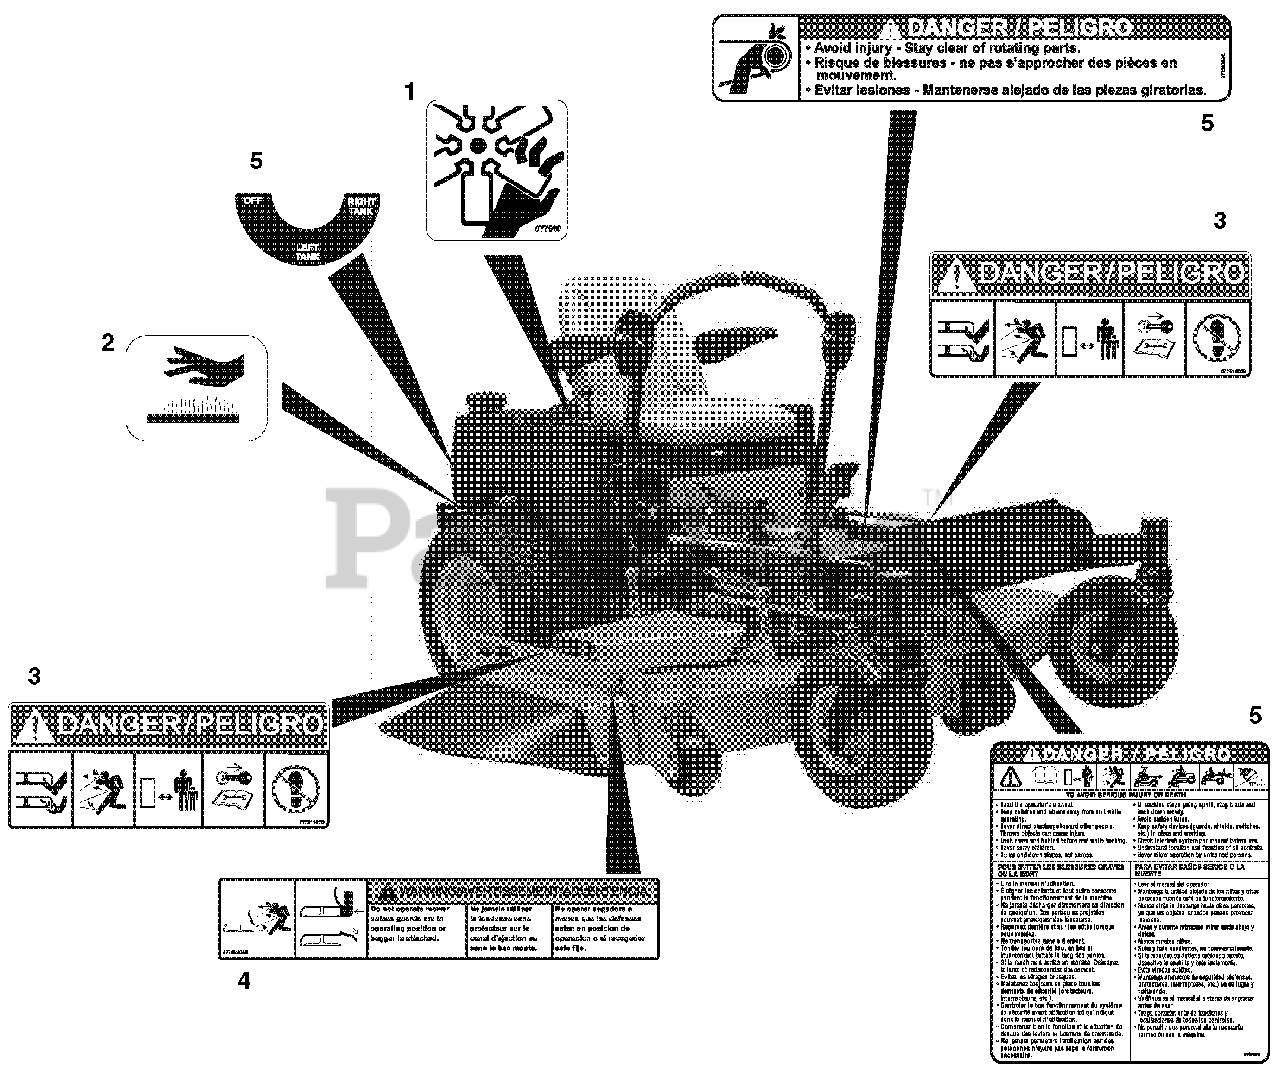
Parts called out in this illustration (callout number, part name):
1	Decal, Danger Fan
2	Decal, Hot Surface
3	Decal, Mower Pan Head Danger
4	Decal, Warning
5	Set, Decal Common Danger/Fuel
